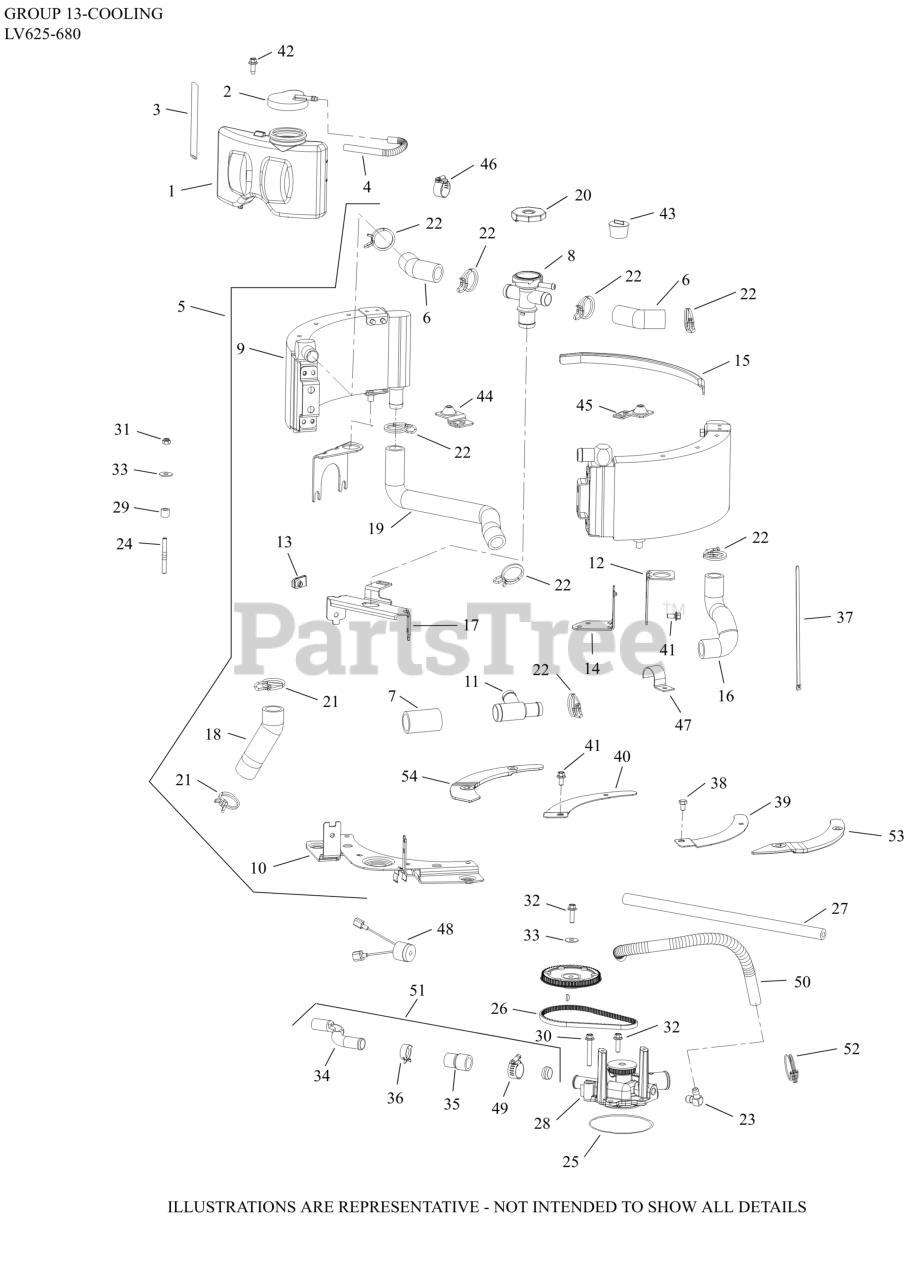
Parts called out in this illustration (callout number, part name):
1	TANK, OVERFLOW (BOTTLE)-DISC.
2	CAP, OVERFLOW BOTTLE - (#DISC)
3	HOSE, WATER BOTTLE
4	HOSE, WATER BOTTLE - DISCONTINUED
5	RADIATOR ASSEMBLY - DISCONTINUED
6	HOSE, INLET-DISCONTINUED
7	HOSE, OUTLET-DISCONTINUED
8	FILLER NECK-DISCONTINUED
9	RADIATOR CORE - DISCONTINUED
10	BRACKET, BOTTOM ATTACHING
11	TEE, HOSE CONNECTOR-DISC.
12	BRACKET, UPPER Z ATTACHING-DISC.
13	U CLIP - DISCONTINUED
14	BRACKET, LOWER Z ATTACHING-DISC.
15	TOP TIE BAR
16	HOSE, OUTLET - (#DSC)
17	BRACKET, TOP ATTACHING
18	HOSE, INLET-DISCONTINUED
19	HOSE, OUTLET-DISCONTINUED
20	CAP, RADIATOR - (#6617309S)
21	CLAMP-DISCONTINUED
23	CONNECTOR
24	STUD, M6X1.0X53 - DISCONTINUED
26	BELT, WATER PUMP
27	HOSE, BY-PASS 13"
28	PUMP ASSEMBLY, WATER - USE 66 393 10-S
29	SLEEVE, INTAKE MANIFOLD - DISC.
30	SCREW, FLG M6X1.0X40-(#DSC)
31	NUT, LOCK M6X1.0
32	SCREW, FLG M6x1.0x20
33	WASHER, FLAT 1/4"
34	TUBE, CROSSOVER (METAL)
35	TUBE, CROSSOVER (RUBBER)
36	CLAMP, CONSTANT TENSION BAND
37	TIE STRAP, LWR RADIATOR HOSE
38	SCREW, CAP M6X1.0X10
39	PLATE, LEFT BLOCK OFF
40	PLATE, RIGHT BLOCK OFF - DISC.
41	SCREW, FLG M6X1.0X12
42	SCREW-USE 25 086 404-S
43	CAP, PLASTIC
44	BRACKET, LEFT KIDNEY
45	BRACKET, RIGHT KIDNEY
46	CLAMP, HOSE-USE 25 237 32-S
47	CLIP,LWR RADIATOR HOSE HALF-DISC.
48	ALARM, COOLANT OVERHEAT-(#DSC)
